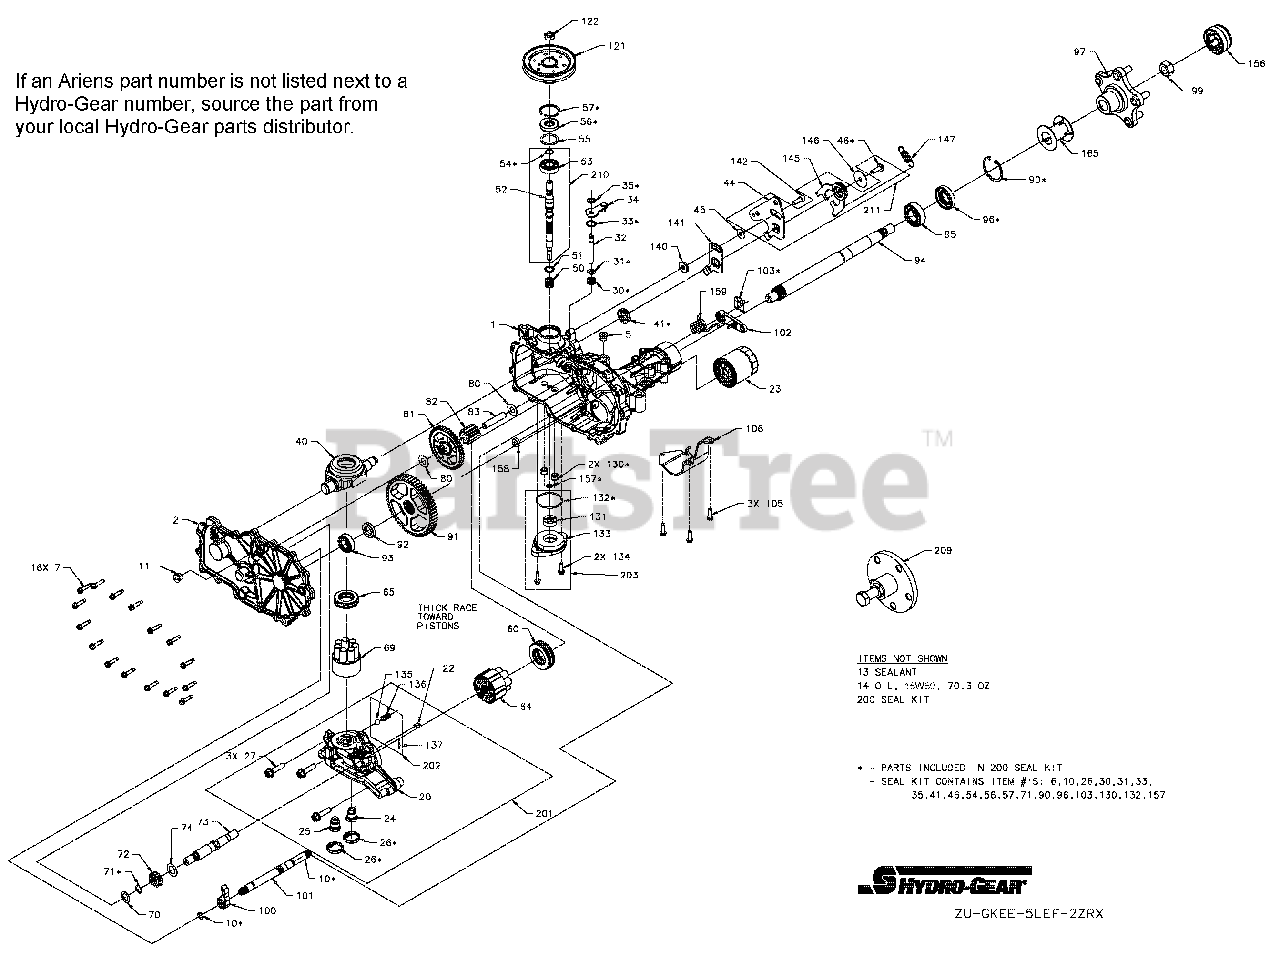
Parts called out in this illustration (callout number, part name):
7	HFHCS 1/4-20 x 1.125"
13	SEALANT
14	SYNTHETIC OIL, 15W50
22	PLATE, BYPASS
23	FILTER, OIL
26	SEAL, PLUG 1.250 x .250
30	SEAL, LIP .375 x .75 x .25
31	RING, RET .375 EXTRNL
33	RING, RET .750 INTRNL
34	ARM, BYPASS
35	RING, RTNG .375 EXT
40	TRUNNION, SWASHPLATE
41	SEAL, LIP 12 x 32 x 7
45	WASHER .34 x .88 x .06
46	TWHCS 5/16-24 x 1.00 (PATCH)
50	SPRING, BLOCK
51	WASHER-FLAT .59 x .79 x .04
55	WASHER 1.23 x 1.56 x .04
56	SEAL, LIP 17 x 40 x 7
57	RING, RETAINING
60	BEARING, THRUST
64	ASS'Y, CYLINDER BLOCK, 16cc
65	BRG, THRUST PLASTIC CAGE
69	ASS'Y, BLOCK 7 PISTON
70	WASHER .63 x 1.0 x .05
71	RING, RETAINING_.625
74	WASHER .72 x 1.16 x .04
80	WASHER .5 x 1.0 x .03
83	JACK SHAFT (PIN)
90	RING, RET 2.06 INT
95	BRG, BALL 25.4 x 52 x 15
96	SEAL, LIP 1.000 x 2.049 x .375
97	KIT, HUB, 5 BOLT
99	NUT, HEX LOCK 3/4-16
102	KIT, HANDLE, ACTUATING
103	CLIP, RETAINING
122	NUT,HEX JAM 1/2-20 W/ PATCH
130	TUBE, CONNECTING
132	O-RING, -137, 0.103 x 2.050
133	COVER, CHARGE PUMP
141	ARM, NEUTRAL RIGHT
142	SHCS 5/16-24 x 1 PATCH
146	WASHER, .343 x 1.500 x .062
147	SPRING, EXTNSN RTN-34LBS
157	SEAL, LIP 8 x 12 x 3 VC
159	SPRING, TORSION CCW
165	TUBE, AXLE 2.04
201	KIT, CENTER SECTION, RH, CHRG
203	KIT, CHARGE PUMP
210	KIT, INPUT SHAFT
211	KIT, RTN, CW
